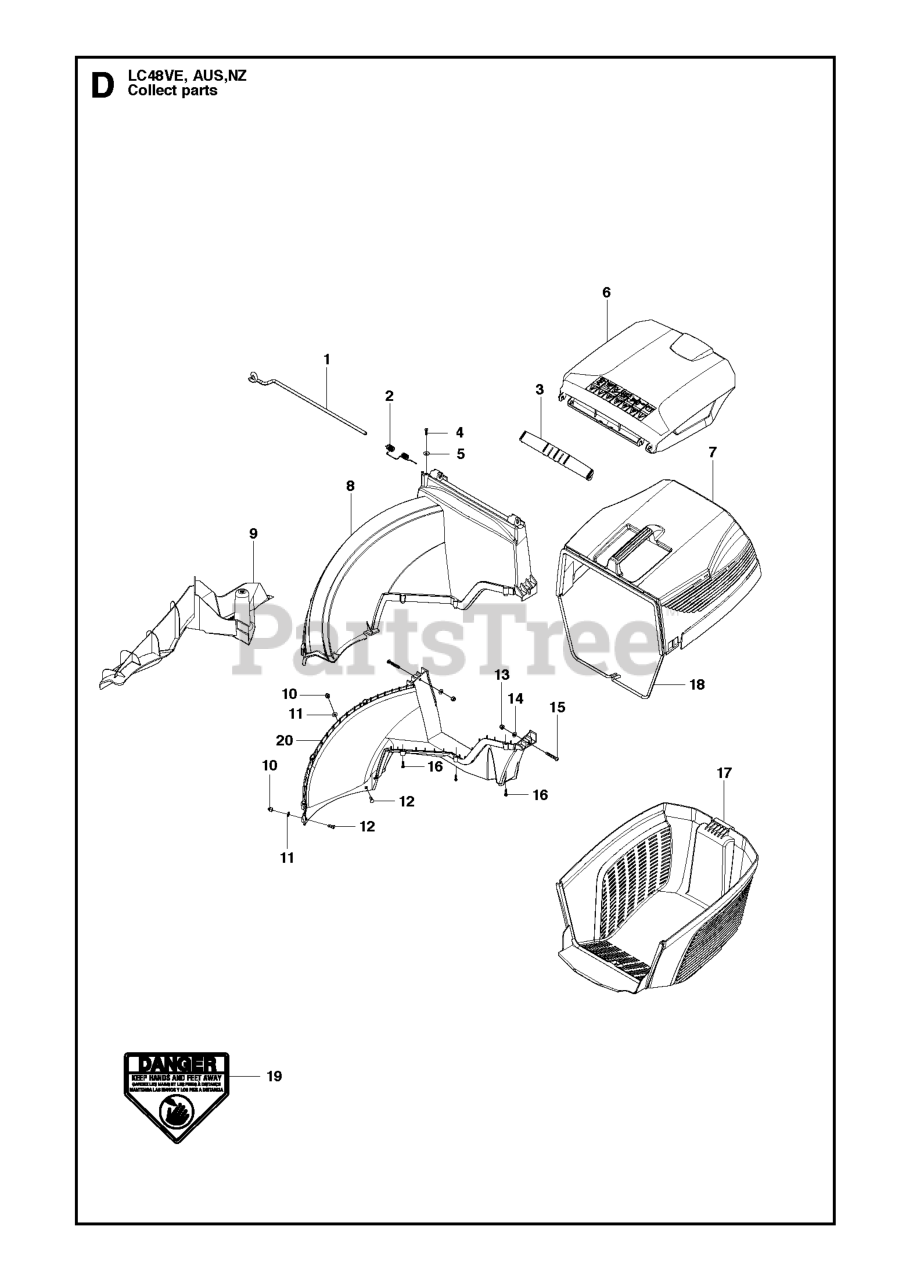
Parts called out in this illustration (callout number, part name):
1	AXLE HATCH REAR DISCHARGE
2	SPRING SAFETY FLAP A009
4	SCREW ITXPANT T50X16 ZN/FE (A
6	HATCH REAR DISCHARGE
7	GRASSBAG UPPER
8	CHUTE UPPER A009
16	SCREW ITXPANT T50X16 ZN/FE (A
17	GRASSBAG LOWER
19	LABEL, DANGER
20	CHUTE LOWER A009
